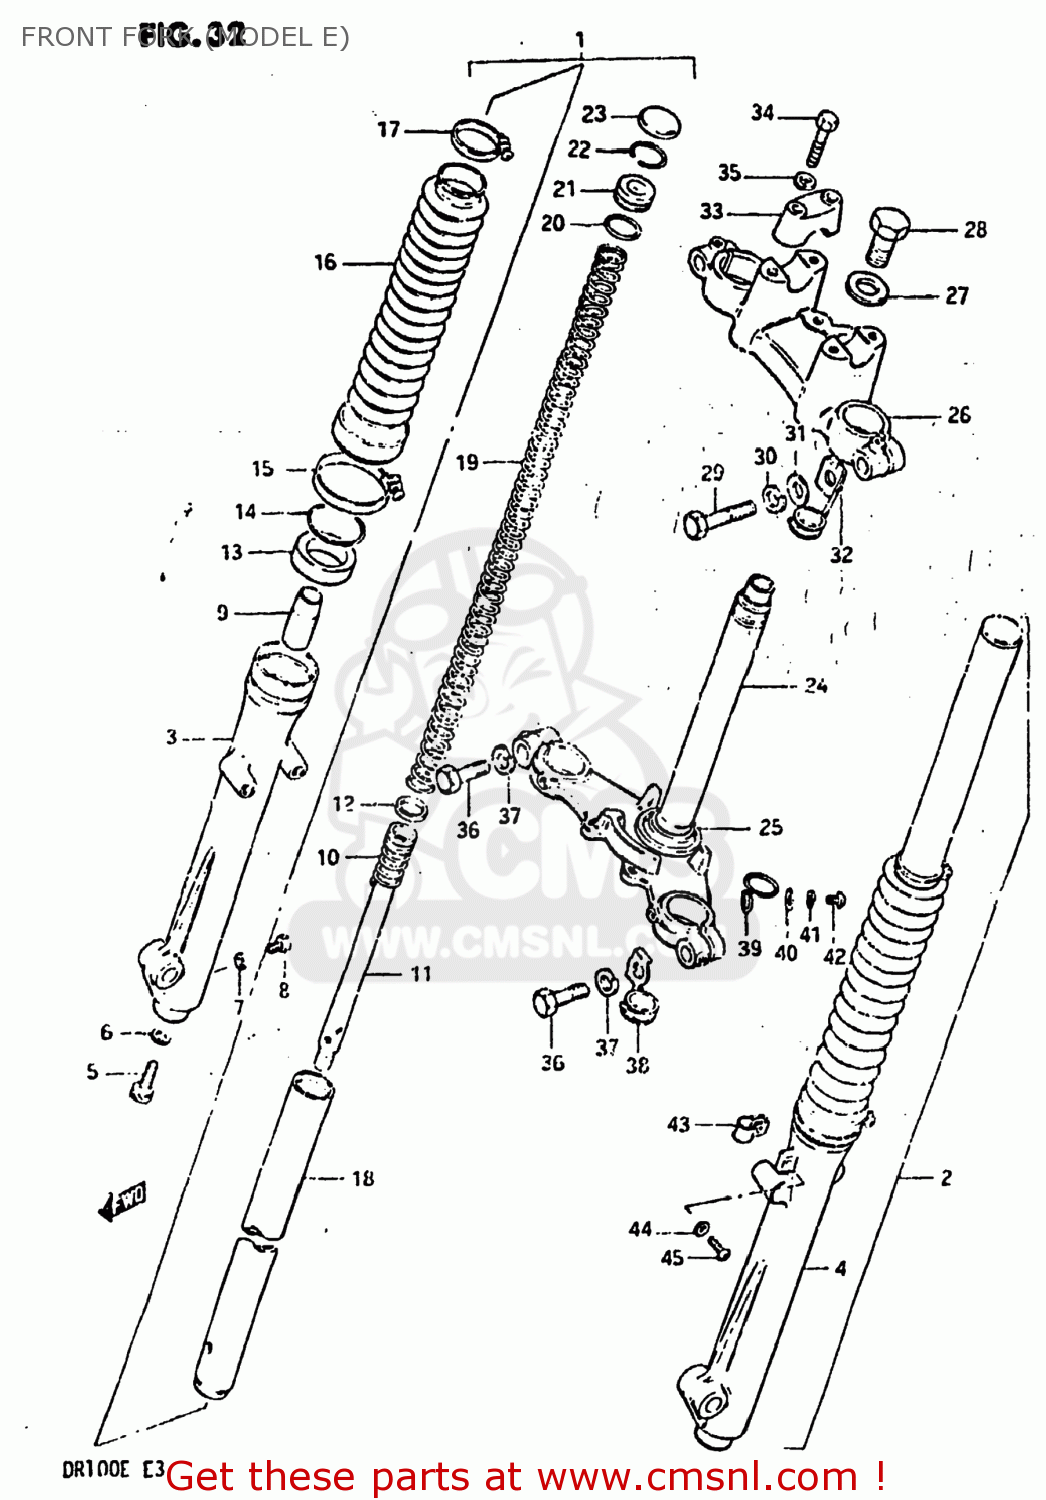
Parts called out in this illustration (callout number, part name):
1	DAMPER ASSEMBLY,RIGHT
2	DAMPER ASSEMBLY,LEFT
3	TUBE,OUTER,RIGHT
4	TUBE,FORK,LEFT,OUTER
5	BOLT(8X27)
6	GASKET (NAS)
7	GASKET,DRAIN,PLUG (NAS)
8	BOLT
9	PIECE,OIL LOCK
10	SPRING,REBOUND
11	CYLINDER,FRONT FORK
12	RING
13	SEAL,OIL
14	CIRCLIP,FORK OIL SEAL
15	BAND,FRONT FORK BOOT
16	BOOT,FR FORK COVER
17	BAND,FRONT FORK BOOT
18	TUBE,FORK,INNER
19	SPRING,FRONT FORK
20	O RING
21	SEAT,SPRING
22	RING,STOPPER
23	CAP,FR FORK
24	STEM,STEERING
25	RACE,STEERING OUTER LWR
26	HEAD,STEERING STEM
27	WASHER,STEM HEAD(10.5X30X3.2)
28	BOLT,STEERING STEM HEAD
29	BOLT 10X40
30	LOCK WASHER
31	WASHER
32	GUIDE,CABLE
33	HOLDER,HANDLEBAR
34	BOLT
35	LOCK WASHER
36	BOLT,M10X1.25X
37	LOCK WASHER
38	GUIDE,CABLE
39	CLIP
40	WASHER
41	LOCK WASHER
42	SCREW 6X12
43	CLIP,FR BRAKE CABLE
44	LOCK WASHER
45	SCREW
